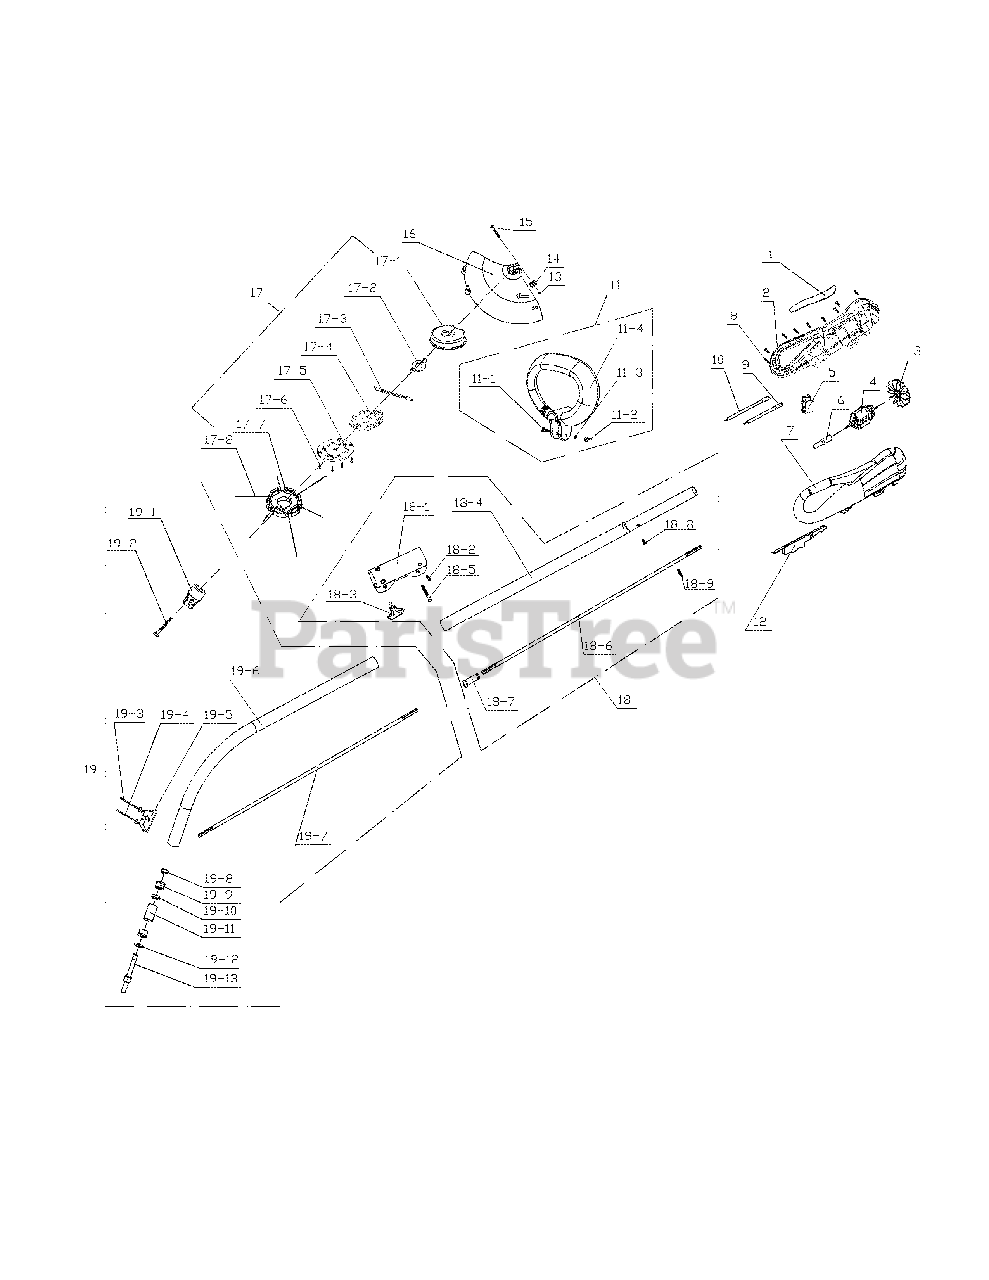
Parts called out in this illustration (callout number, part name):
1	READ HOUSING
2	HOUSING (R)
6	CONNECTING HEAD ASS'Y
7	HOUSING (L)
11	HANDLE ASS'Y
17	CUTTING LINE ASS'Y
17-4	PUSH BUTTON
17-5	REX HEAD COVER
17-7	SPOOL CARRIER
17-8	CUTTING LINE
18	BAG BEHIND ASS'Y
18-1	CONNECTOR
18-4	BAG BEHIND
18-6	BACK SHAFT FLEX
18-7	CONNECTOR
18-9	GEAR SPRING
19	Order components
19-6	BAG FRONT
19-7	SHAFT FLEX ASS'Y
19-8	STEEL RING
19-13	CONNECTING HEAD
